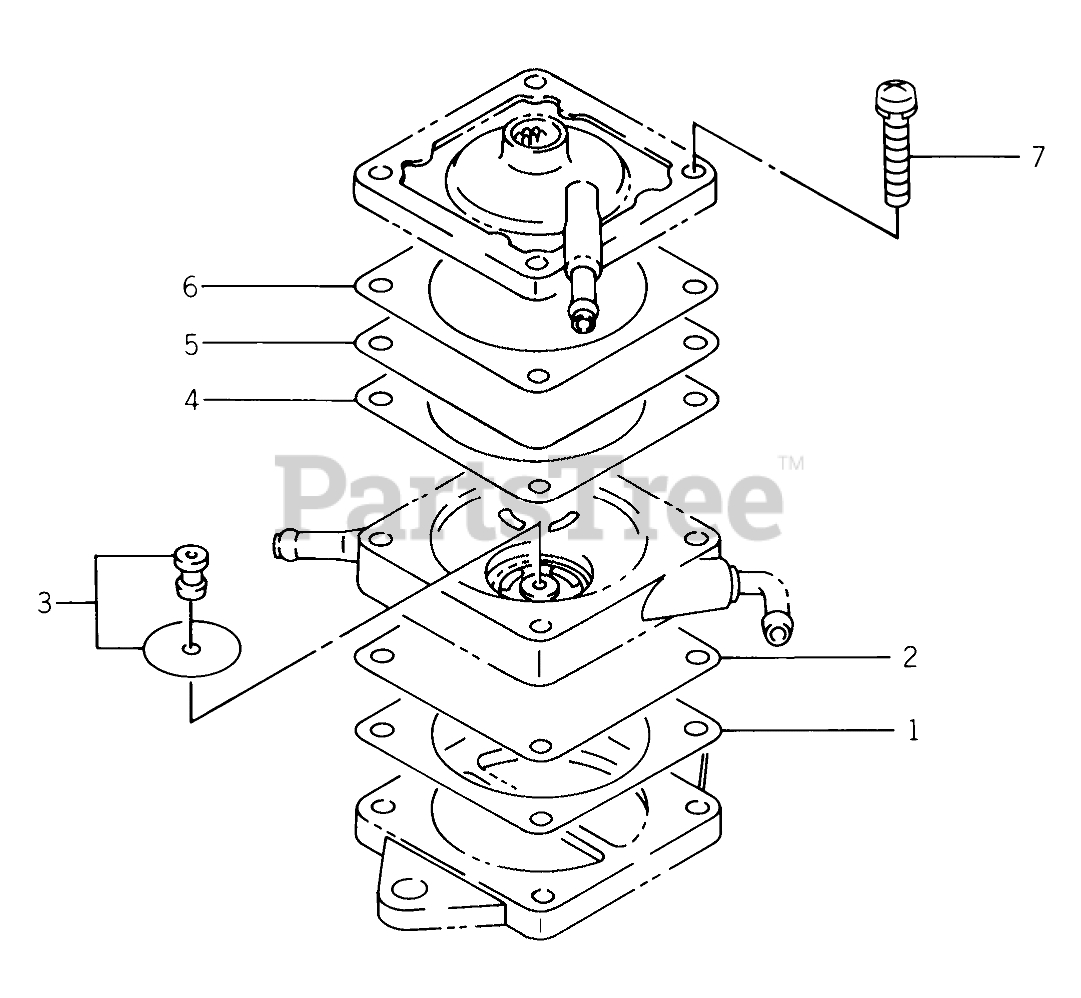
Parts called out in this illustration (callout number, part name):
1	GASKET
2	DIAPHRAGM
3	ASS'Y-VALVE
4	GASKET
5	DIAPHRAGM
6	GASKET
7	SCREW
